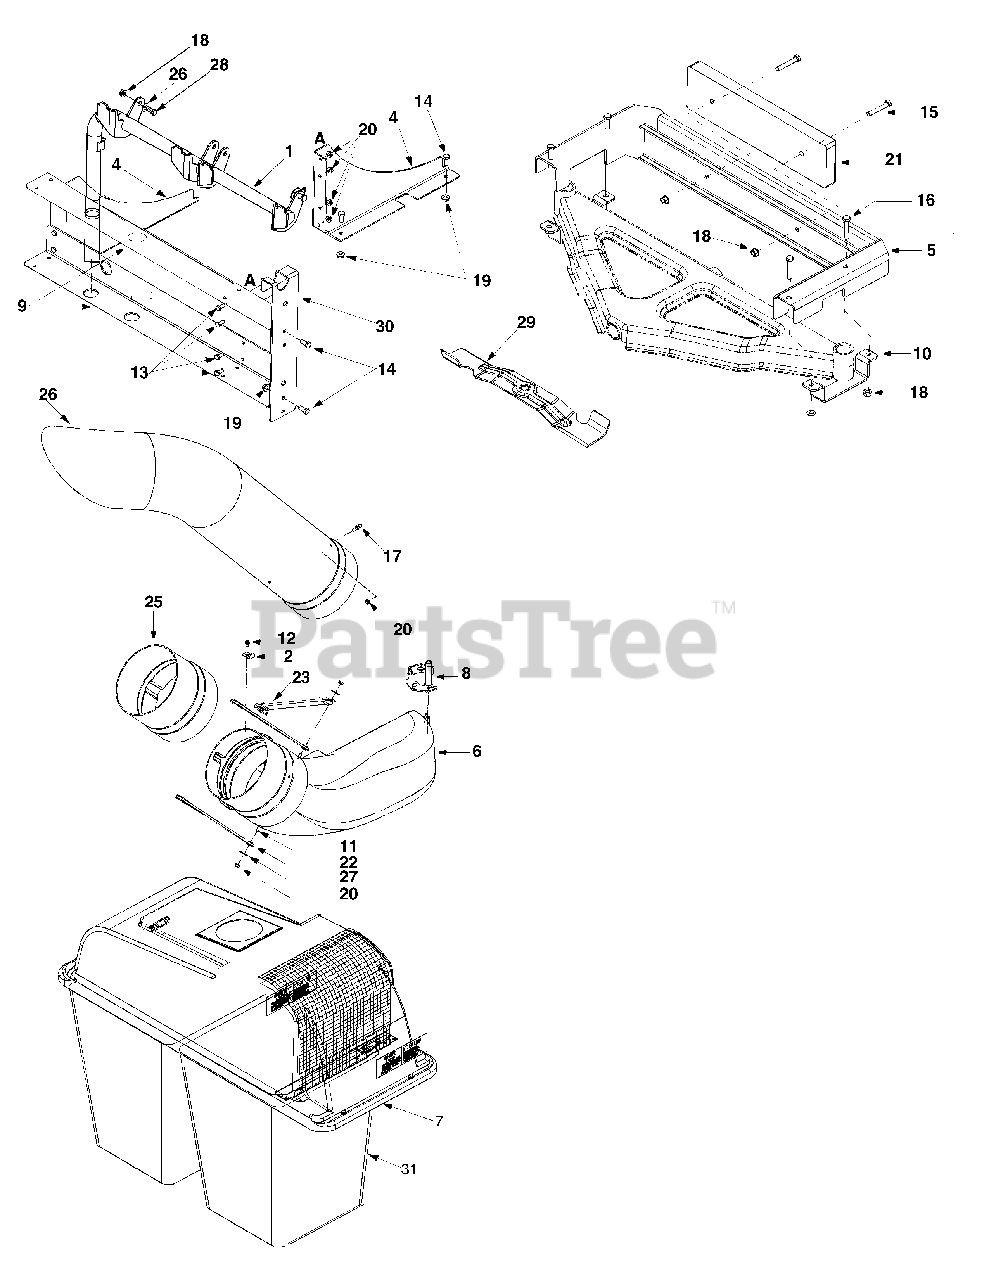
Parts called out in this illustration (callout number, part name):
2	Retainer Hook Bracket
3	Catcher Mounting Assembly RH
6	Chute Elbow
7	Grasscatcher Cover Assembly
11	Hex Bolt 1/4-20 x 1.0
12	TT Screw 1/4-20 x 0.5
13	Hex Bolt 1/4-20 x 0.620
14	Hex Bolt 5/16-18 x 0.75
15	Hex Bolt 3/8-16 x 2.25
16	Hex Bolt 3/8-16 x 2.0
17	Grasscatcher Pin
18	Flange Lock Nut 3/8-16
19	Flange Lock Nut 5/16-18
20	Flange Lock Nut 1/4-20
21	Weight Bar
22	Chute Strap
23	Chute Strap
24	Chute Tube
25	Chute Extension
26	Bell Washer
27	Flat Washer
28	Shoulder Screw 3/8-16
31	Grassbag Assembly Parts
31	Screw, #10-24 x .5
31	Hex Sems Nut, 10-24
31	Bag
31	Self Tapping Screw, 5/16-18 x .625
